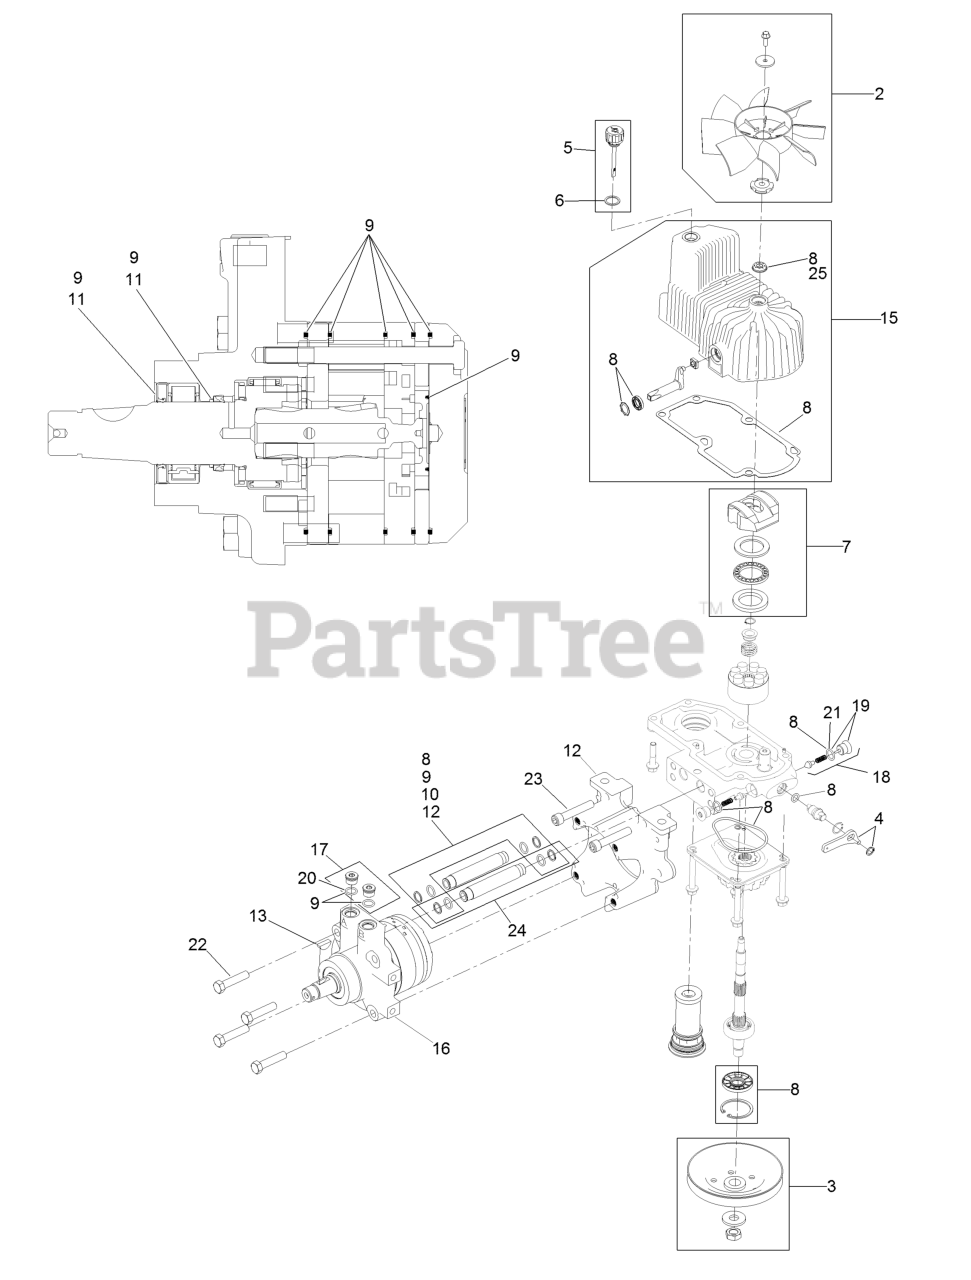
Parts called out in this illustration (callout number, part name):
2	Fan Kit
3	Pulley Kit
4	Handle-Bypass Valve, Hydro
5	Dipstick-Hydro W/Gasket
6	Gasket-Dipstick, Hydro
7	Swash Block Kit
8	Pump Seal Kit
9	Motor Seal Kit
10	Tube Seal Kit
11	Output Shaft Seal Kit
12	Nose Cup-Uht
13	Key-Woodruff
15	Housing-LH
16	Motor-Hydraulic LH 240Cc
17	Magnetic Plugs Service Kit
18	Check Valve ASM
19	Plug-Check (W/O-Ring)
21	O-Ring-Check Valve
22	Screw HH
23	Screw-HSH
24	Hydraulic Tube Kit
25	Seal-Fan Drive
99	Flow Test Kit
99	Puller-Pulley
